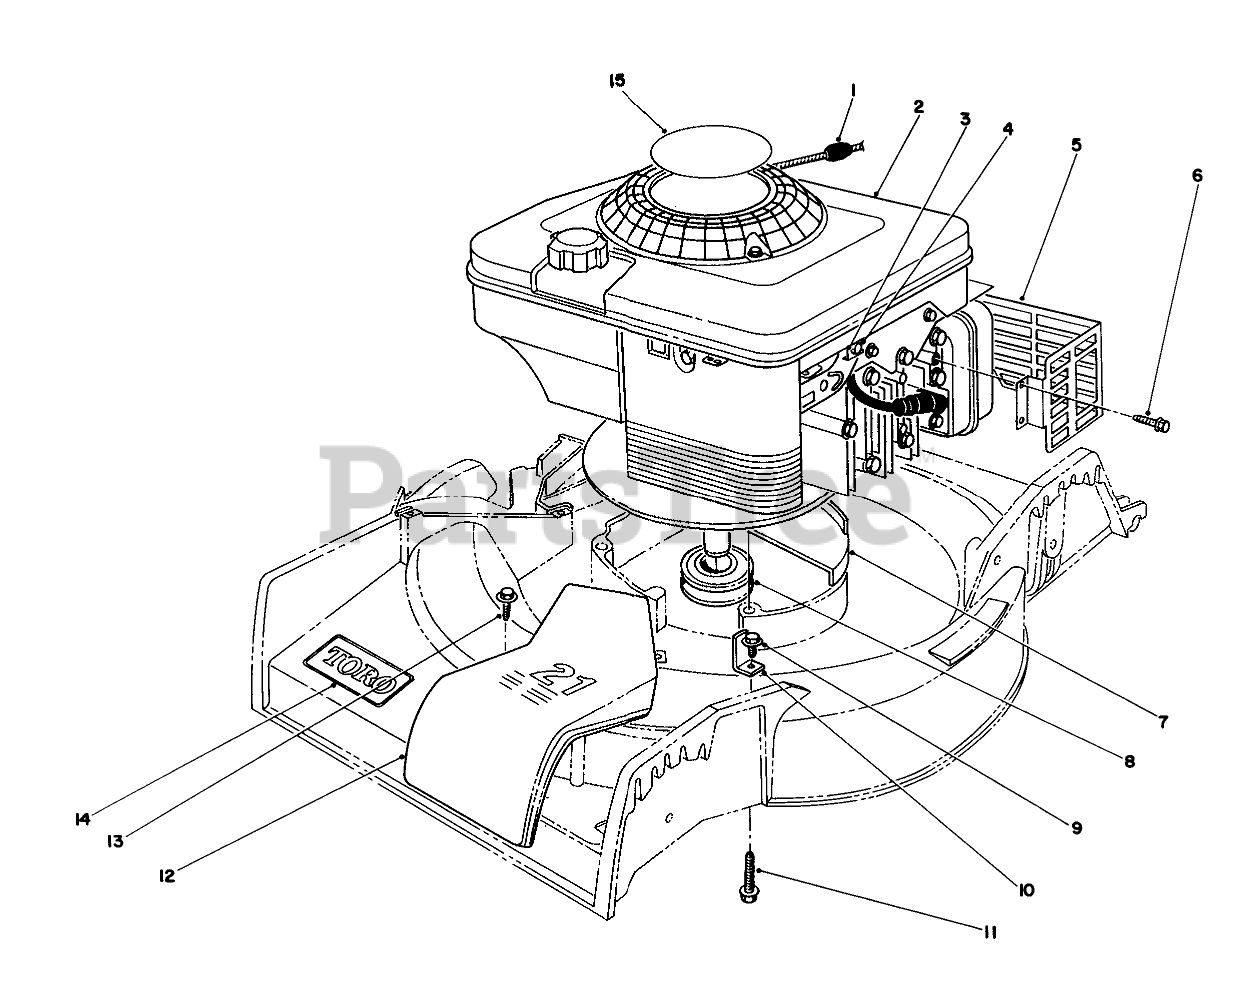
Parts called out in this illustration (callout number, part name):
1	STOP-ROPE
2	Engine
3	CLAMP-CASING
4	Screw
5	SHIELD-MUFFLER
6	SCREW-HWH
7	HOUSING CAP
8	PULLEY-DRIVER
9	SCREW-HWHTF
10	BELT GUIDE
11	THD FORM SCREW
12	BELT COVER 21" S D
13	SCREW
14	DECAL
15	DECAL - ENGINE
